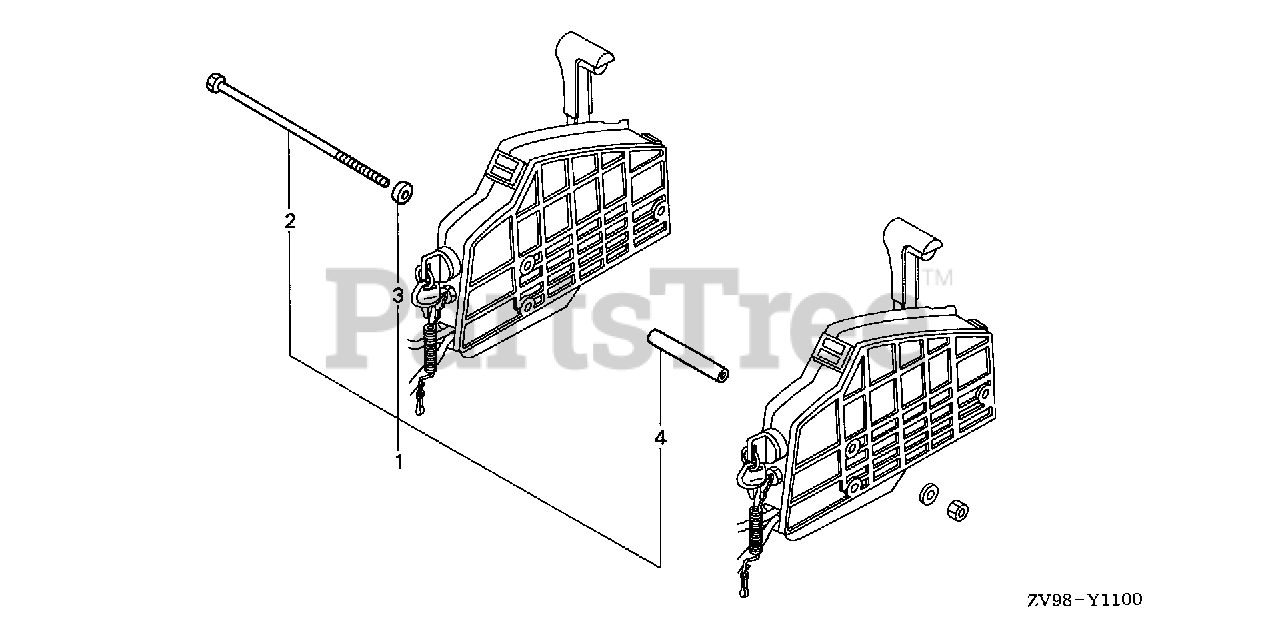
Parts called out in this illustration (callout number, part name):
1	BOLT KIT, SIDE REMOTE CONTROL
2	BOLT, SPECIAL (6X220)
3	COLLAR, DISTANCE (A)
4	COLLAR, DISTANCE (B)
